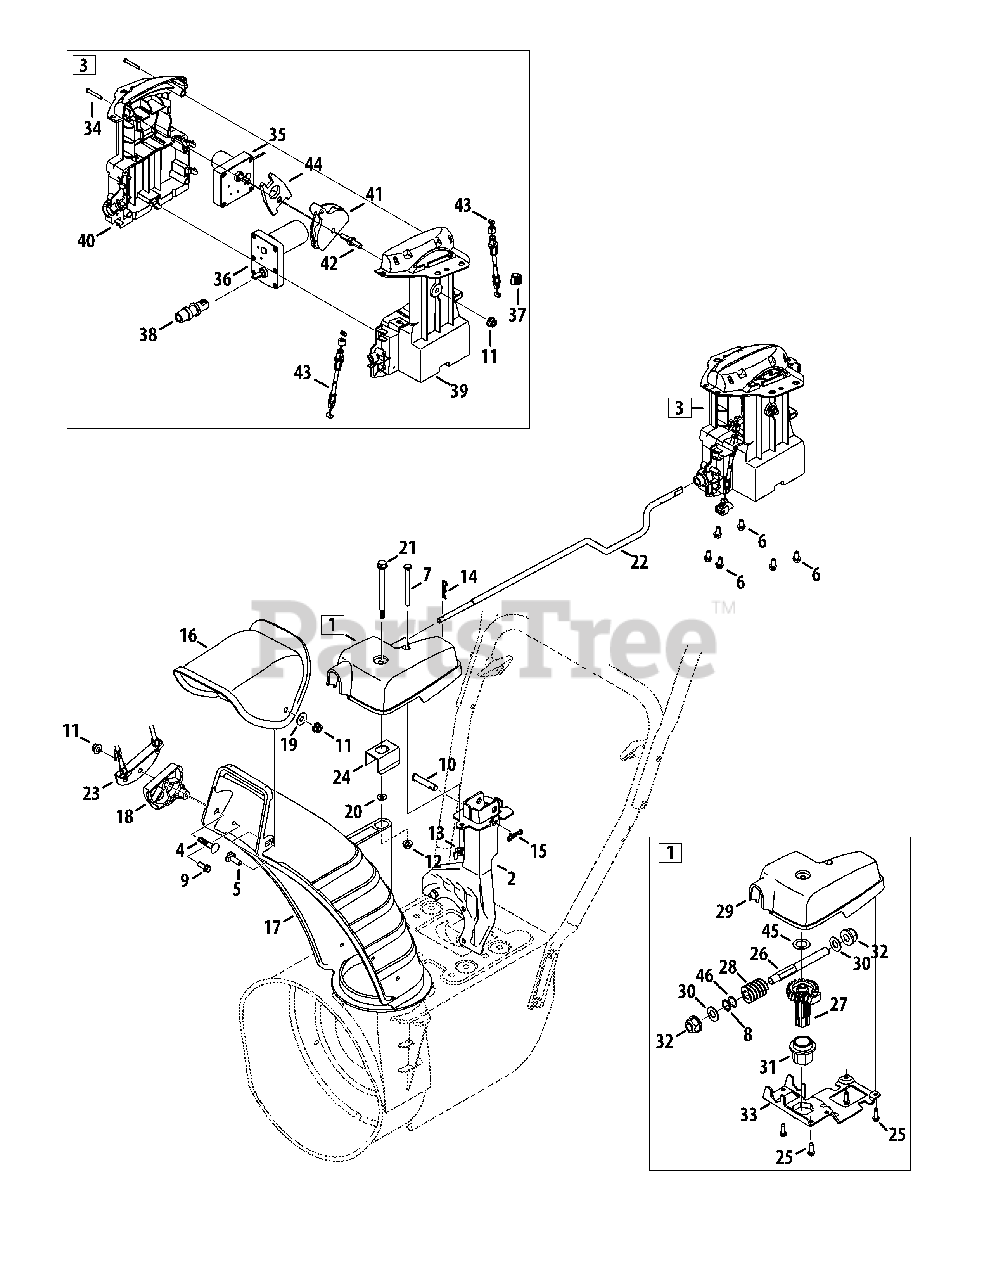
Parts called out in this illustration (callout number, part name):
1	Gearbox Assembly, Chute Rotation
2	Chute Support Bracket
3	Chute Assembly, 4-Way Elec.
4	Bolt, Carriage, 5/16-18 x 1.50
5	Bolt, Carrier, 5/16-18 x 1.00
6	Screw, HL, 1/4-15 x 0.50
7	Hex Head Screw, 1/4-20 x 3.00
8	Shim Washer, .504 x .700 x .020
9	Screw, HL, 1/4-15 x 0.750
10	Clevis Pin, 3/8 x 1.87
11	Nut, Flangelock, 5/16-18
12	Nut, Flangelock, 1/4-20
13	Wing Nut, 1/4-20
14	Internal Cotter Pin
15	Bow-Tie Cotter Pin
16	Chute, Upper
17	Chute, Lower
18	Cable Guide, Chute Tilt
19	Washer, Flat, .349 x .879
20	Washer, Flat, .25 x .630
21	Screw, Shoulder, .312 x 3.5 x 1/4-20
22	Chute Crank Rod
23	Cable Bracket
24	Chute Bracket
25	Screw, 12-16 x .75
30	Flat Washer, .510 x 1.00 x .060
31	Flange Bearing, 1.00 ID
32	Flange Bearing, .50 ID
34	Screw, #10-16 x 1.25
35	Chute Pitch Motor
36	Chute Rotation Motor
37	Cable Clip
38	Electric Chute Coupler
39	Housing, LH
40	Housing, RH
41	Cable Guide
42	Hex Screw, 5/16-18 x .75
43	4-Way Cable
43	Cable Clip
44	Chute Pitch Adapter
45	Shim Washer, .63 x 1.00 x .020
46	Shim Washer, .504 x .700 x .010
